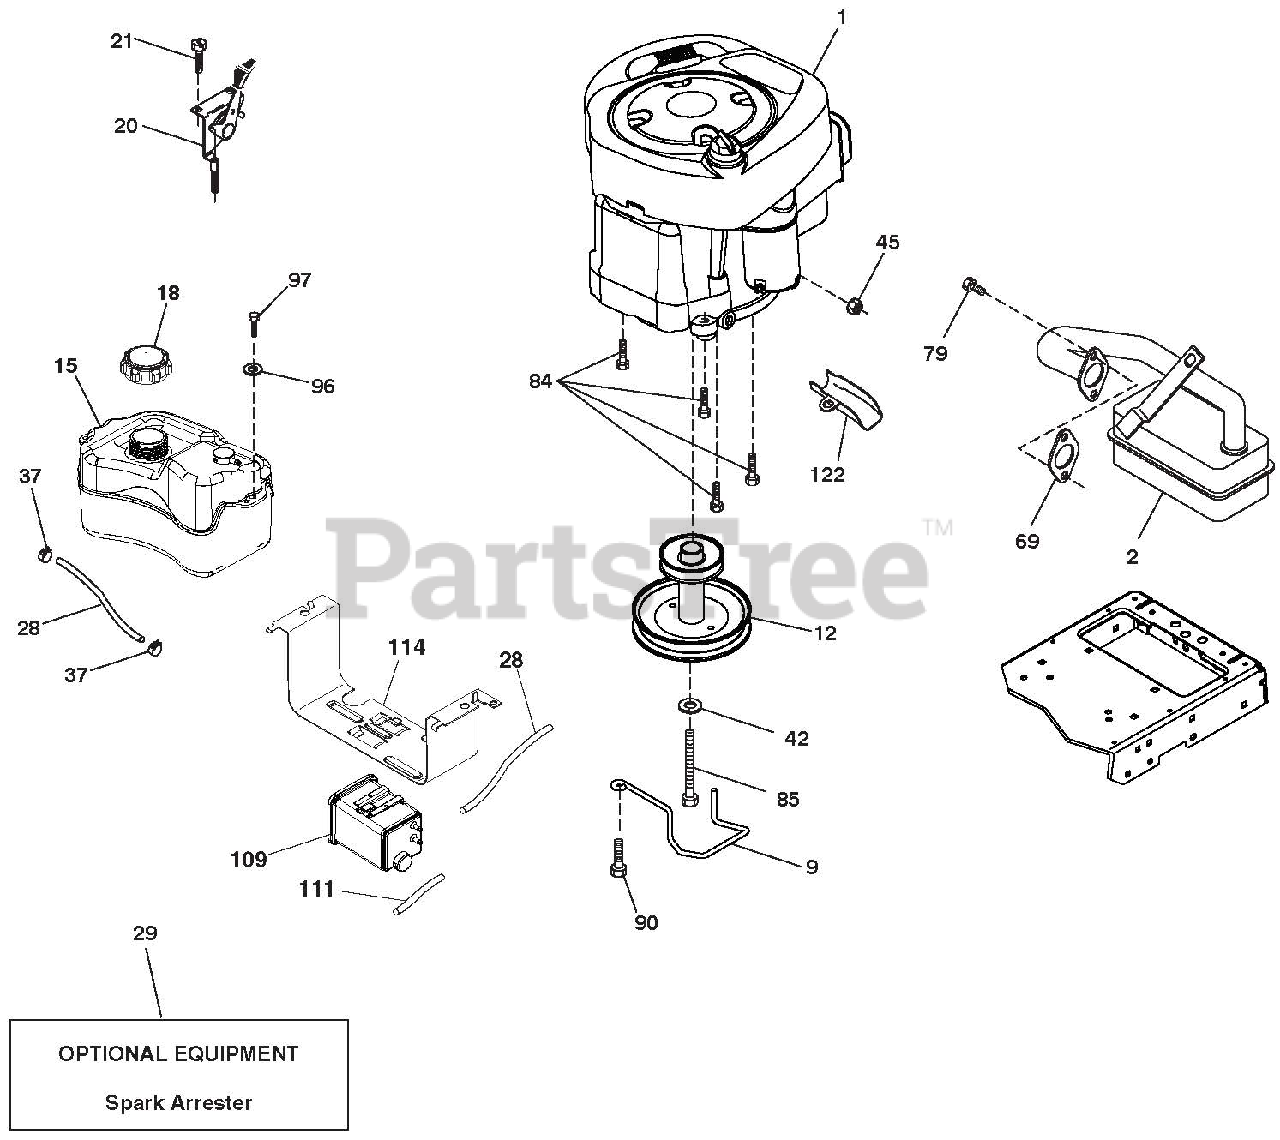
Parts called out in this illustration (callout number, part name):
1	ENGINE BRIGGS MODEL NO.
2	Muffler Exhaust B&S
9	KEEPER BELT ENGINE
12	ENGINE PULLEY
15	TANK FUEL
18	CAP FUEL
20	CONTROL.THROTTLE
28	LINE.FUEL.22"FRONT.EMIS.CA.LP
29	KIT.SPARK ARRESTOR(392390 B&S)
37	CLAMP.HOSE.BLK.
42	WASHER.LOCK.HVY HLCL.SPR.7/16
45	Nut, Keps Hex 1/4-20 unc
69	Gasket Eng 1 313 Id Tin Plated
79	SCREW SOCKET HEAD 5/16-18 X 1
84	Screw 3/8-16 x 1-1/4
85	BOLT.HEX.7/16-20X4XGR5-1.5THR.
90	SCREW.3/8-16X1.SMGML.TAP/R.BLK
96	WASHER.9/32 X 7/8 X 16GA.
97	SCREW.HEXWSH.THDROL.1/4-20X3/4
109	CANISTER.CARBON.FILTER ASM.TEX
111	PURGE.LINE.CARB
114	CRADLE.CANISTER.CARBON
122	Extension Drain Oil
